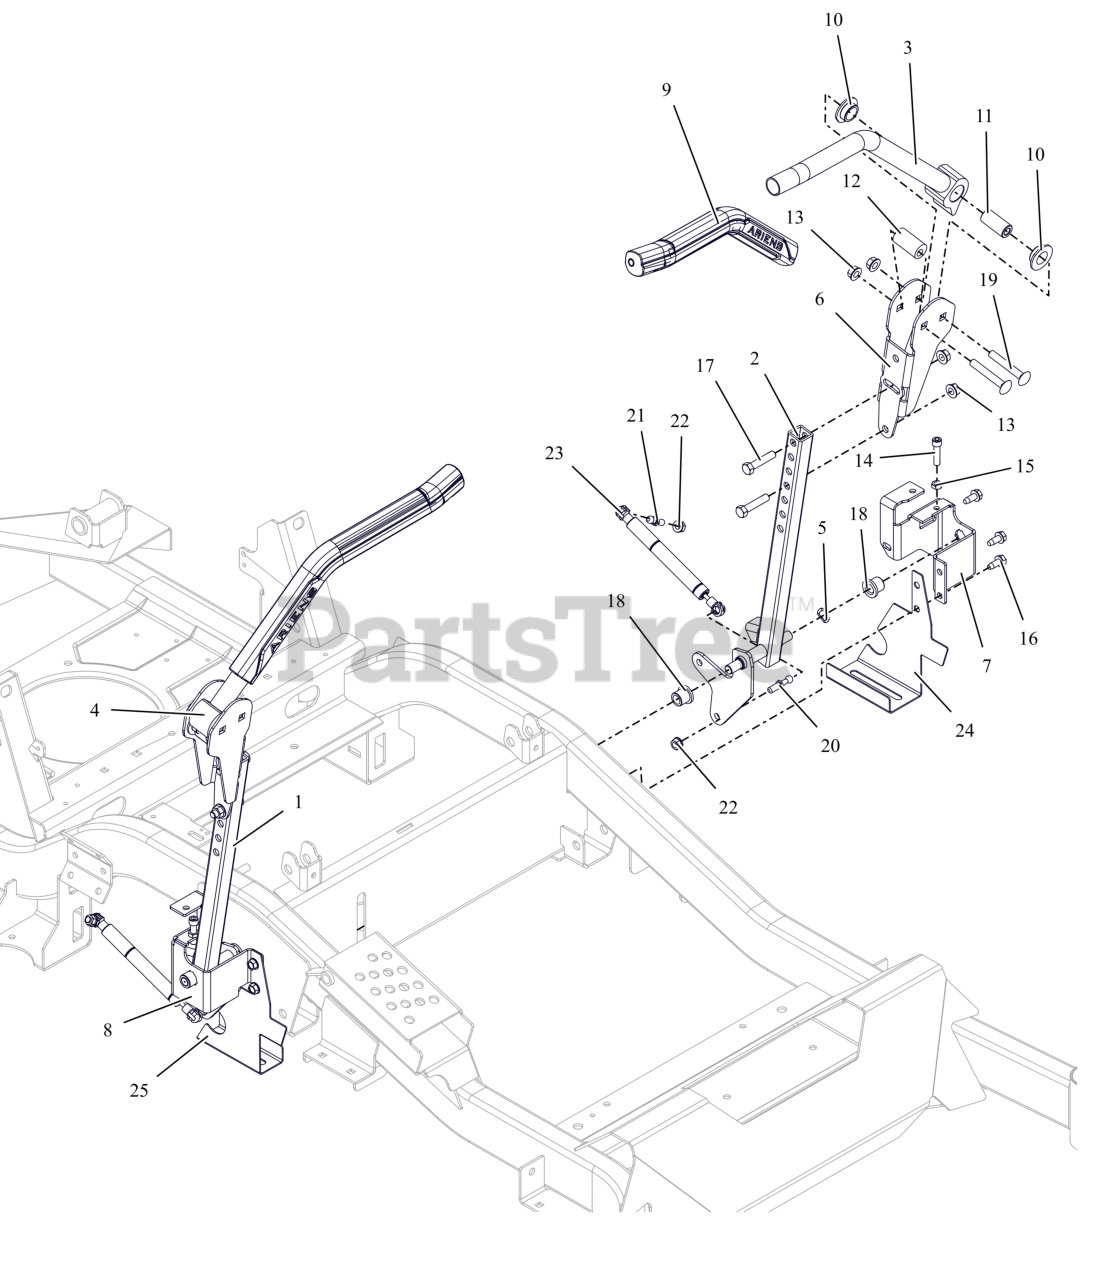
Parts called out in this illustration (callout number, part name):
1	WLDMT, STEERING RH
2	WLDMT, STEERING LH
3	WLDMT, CONTROL HANDLE-LH (BLACK)
4	WLDMT, CONTROL HANDLE-RH (BLACK)
5	WAVE WASHER .531X.781X.125FH
6	ADJ UPPER CONTROL ARM BRKT-BLK
7	BRKT, STEERING ARM MOUNT -LH
8	BRKT, STEERING ARM MOUNT -RH
9	GRIP- HANDLEBAR ARIENS
10	BSHG-FLG .762X1.48X.44 IGLIDER
11	SPACER, STEERING ARM
12	BSHG, ECCENTRIC.406X.875X1.625
13	NUT-LK-TOP-FLG .38-16 ZC120
14	BLT, SHCS .312-18X1.25 G8 SS
15	NUT-JAM .312-18 G2 ZCC
16	SCR,TAP .312-18X.75 HWH TR ZCC
17	BLT, HEX .38-16X1.75 G5 ZCC
18	BHSG-FLG .500X.750X.750X.125
19	BLT, RHSSN.38-16X2.50 G5 ZCC
20	STUD-BALL-THREADED
21	STUD- BALL
22	NUT,LK-CTR-FLG .31-18 GF ZCC
24	GUARD, FRAME RAIL BELT LH
25	GUARD, FRAME RAIL BELT RH
